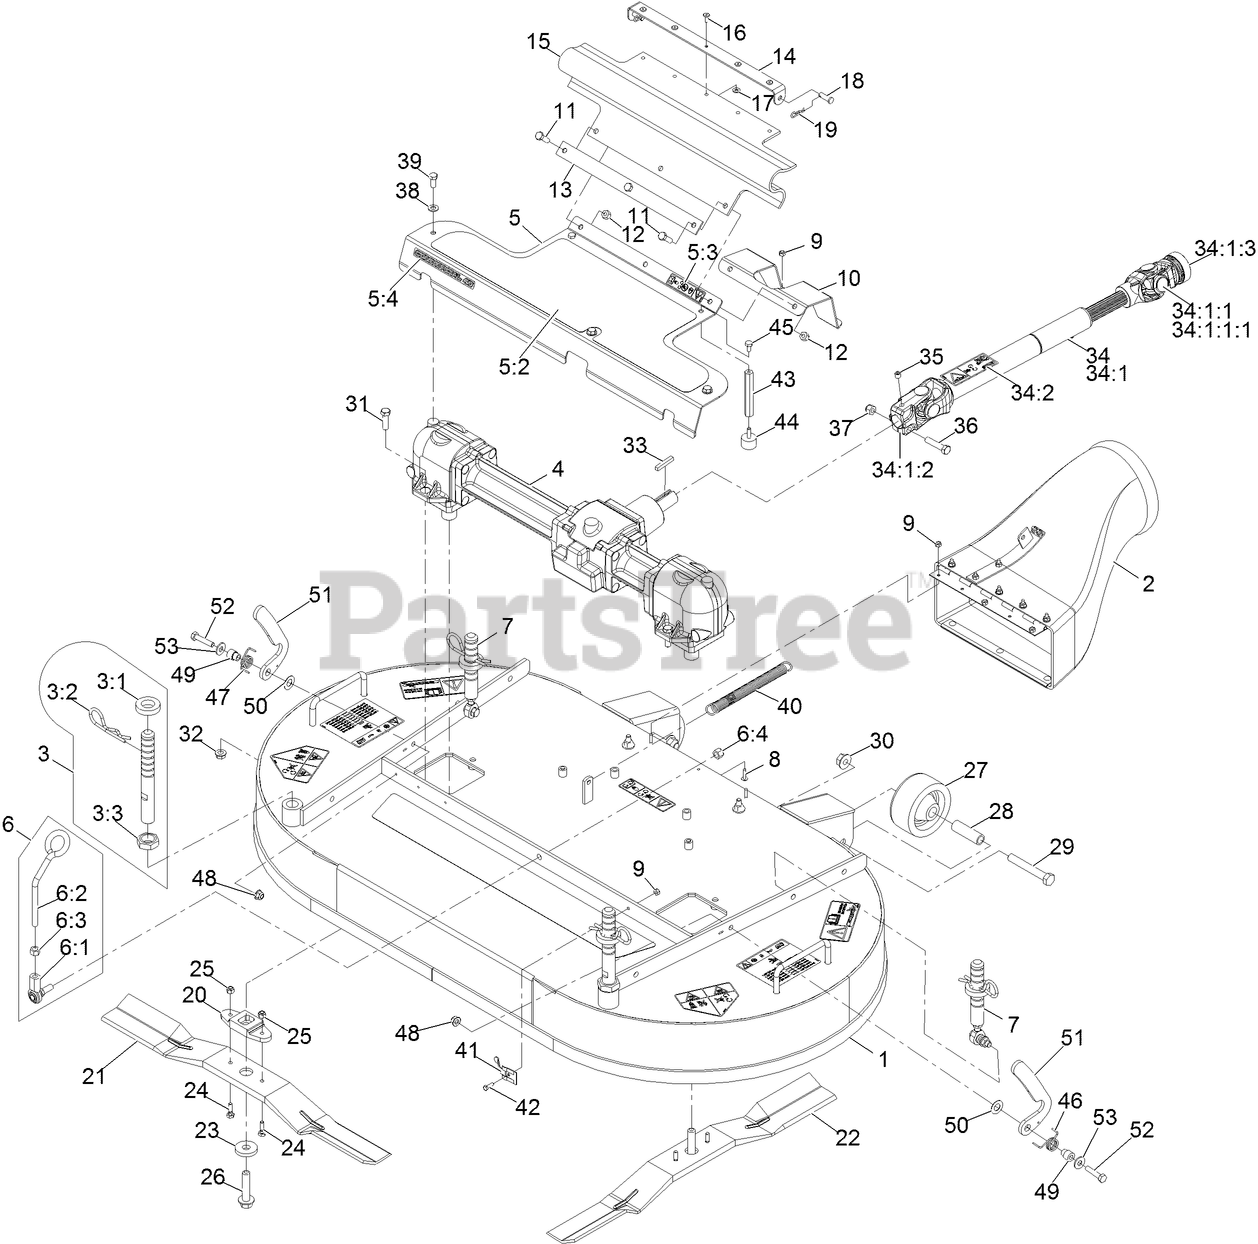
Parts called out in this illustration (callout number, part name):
1	Deck-Cutting 48 W/Decals
2	DISCHARGE TUBE ASM
3	FRONT DECK HEIGHT ADJUST
3:1	SPACER-DECK SUPPORT
3:2	PIN-CUT HEIGHT
3:3	NUT-JAM
4	GEAR BOX ASM
5	ASM,GEARBOX COVER 48 W/DECAL
5:2	PAD-ANTI SKID
5:3	DECAL-DANGER
5:4	DECAL-COMMERCIAL 48
6	DECK LATCH ASM
6:1	BALLJOINT-RH
6:2	LATCH-DECK
6:3	NUT-HEX
6:4	NUT-LOCK
7	REAR DECK HEIGHT ADJUST A
8	SCREW-HEAD, TRUSS
9	NUT-LOCK, NI
10	GUARD-DRIVE SHAFT
11	SCREW-HH
12	NUT-LOCK, NI
13	STRAP-DRIVE, LINE COVER
14	BRACKET-GUARD, PTO
15	GUARD-PTO
16	RIVET-BLIND
17	WASHER-FLAT
18	PIN-CLEVIS
19	PIN-COTTER
20	DRIVER-BLADE
21	BLADE,25 INCH RH
22	BLADE,25 INCH LH
24	BOLT-SHEAR
25	NUT-LOCK, NI
26	BOLT-BLADE
27	ROLLER-DECK
28	SPACER-ROLLER
29	SCREW-HH
30	NUT-HHF
31	SCREW-HH
32	NUT-HHF, WHIZ
33	KEY-SQUARE
34	DRIVE SHAFT ASM
34:1	DRIVE SHAFT-TELESCOPING
34:1:1	U-JOINT KIT
34:1:1:1	FITTING-GREASE
34:1:2	YOKE-KEYED
34:1:3	YOKE-QUICK DISCONNECT
34:2	DECAL-DANGER, DRIVELINE
35	SCREW-SET, HSH
36	SCREW-HH
37	NUT-LOCK, NI
38	WASHER-PLAIN
39	SCREW-HH
40	SPRING-EXTENSION
41	CLIP-DECK, HOLD UP ROD
43	STAND-OFF
45	SCREW-HH
46	SPRING-TORSION, LH (YELLOW)
47	Spring-Torsion, RH
48	NUT-HF, NI
49	COLLAR-BASKET
50	Washer-Plastic
51	Latch - Deck
52	SCREW-HH
53	WASHER-FLAT
